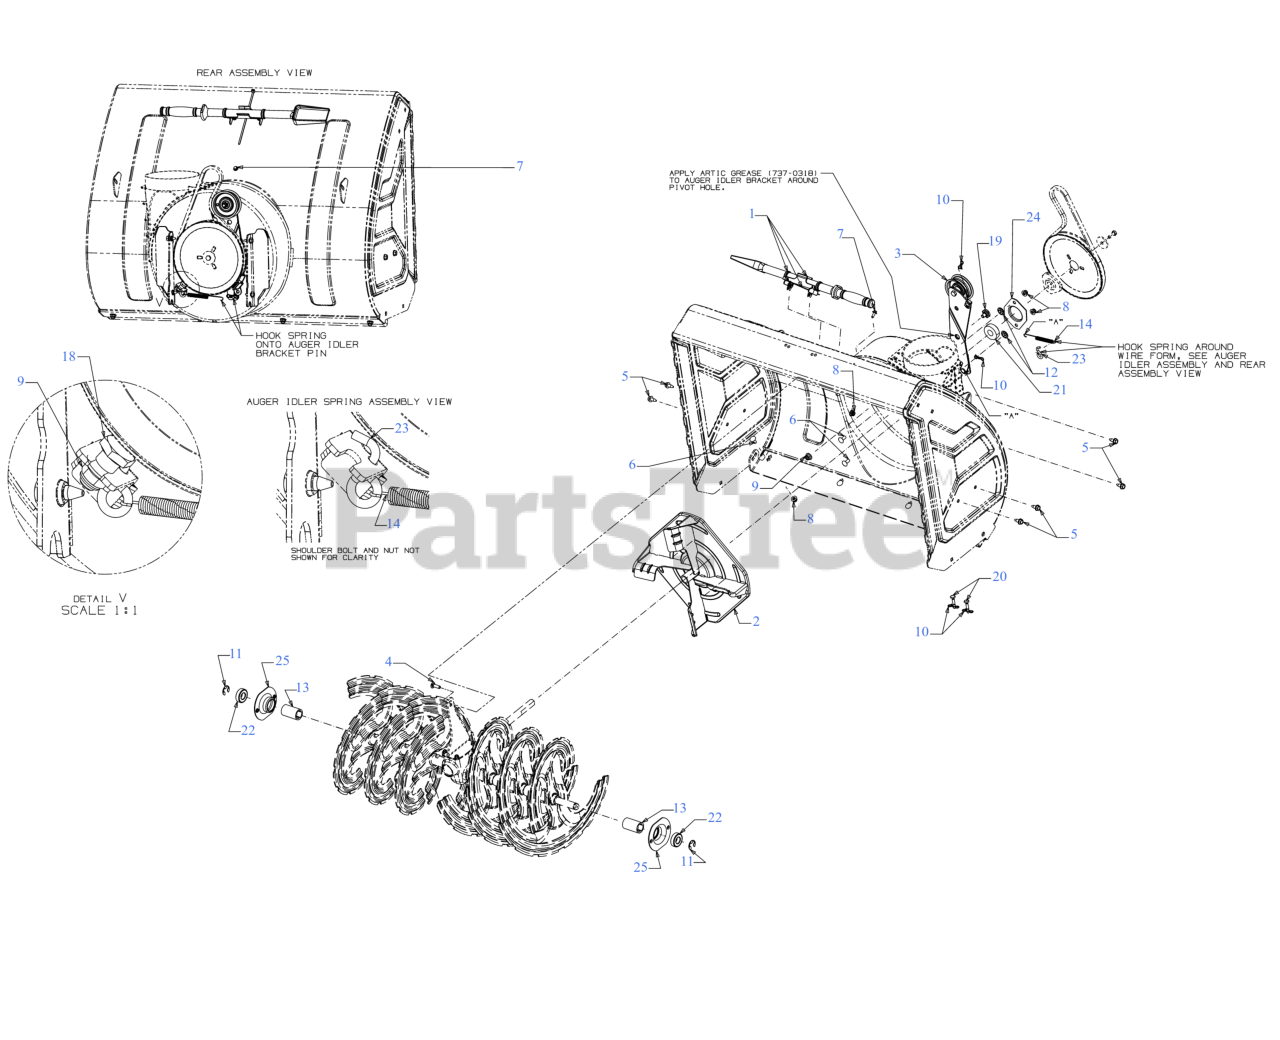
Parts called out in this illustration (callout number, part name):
4	CARRIAGE BOLT 5/16-18 x 1.00
5	SCREW 5/16-18 x .750
6	CARRIAGE BOLT 5/16-18 x .75
7	SCREW M6-1 x .625
8	FLANGE LOCK NUT 5/16-18
10	BOW TIE COTTER PIN 1/4-5/16
11	E-RING
12	PUSH NUT
13	SPACER 1.25 x .75 x 2.085
14	EXTENSION SPRING .38 OD x 4.59
18	SHOULDER SCREW .498 DIA x .340
19	SHOULDER SCREW .625 DIA x .163
20	SHEAR PIN .25 x 1.50 GR2
21	BEARING W/OUT COLLAR
22	BALL BEARING
23	ROD SPRING HOOK
24	BEARING HOUSING 1.85 ID
